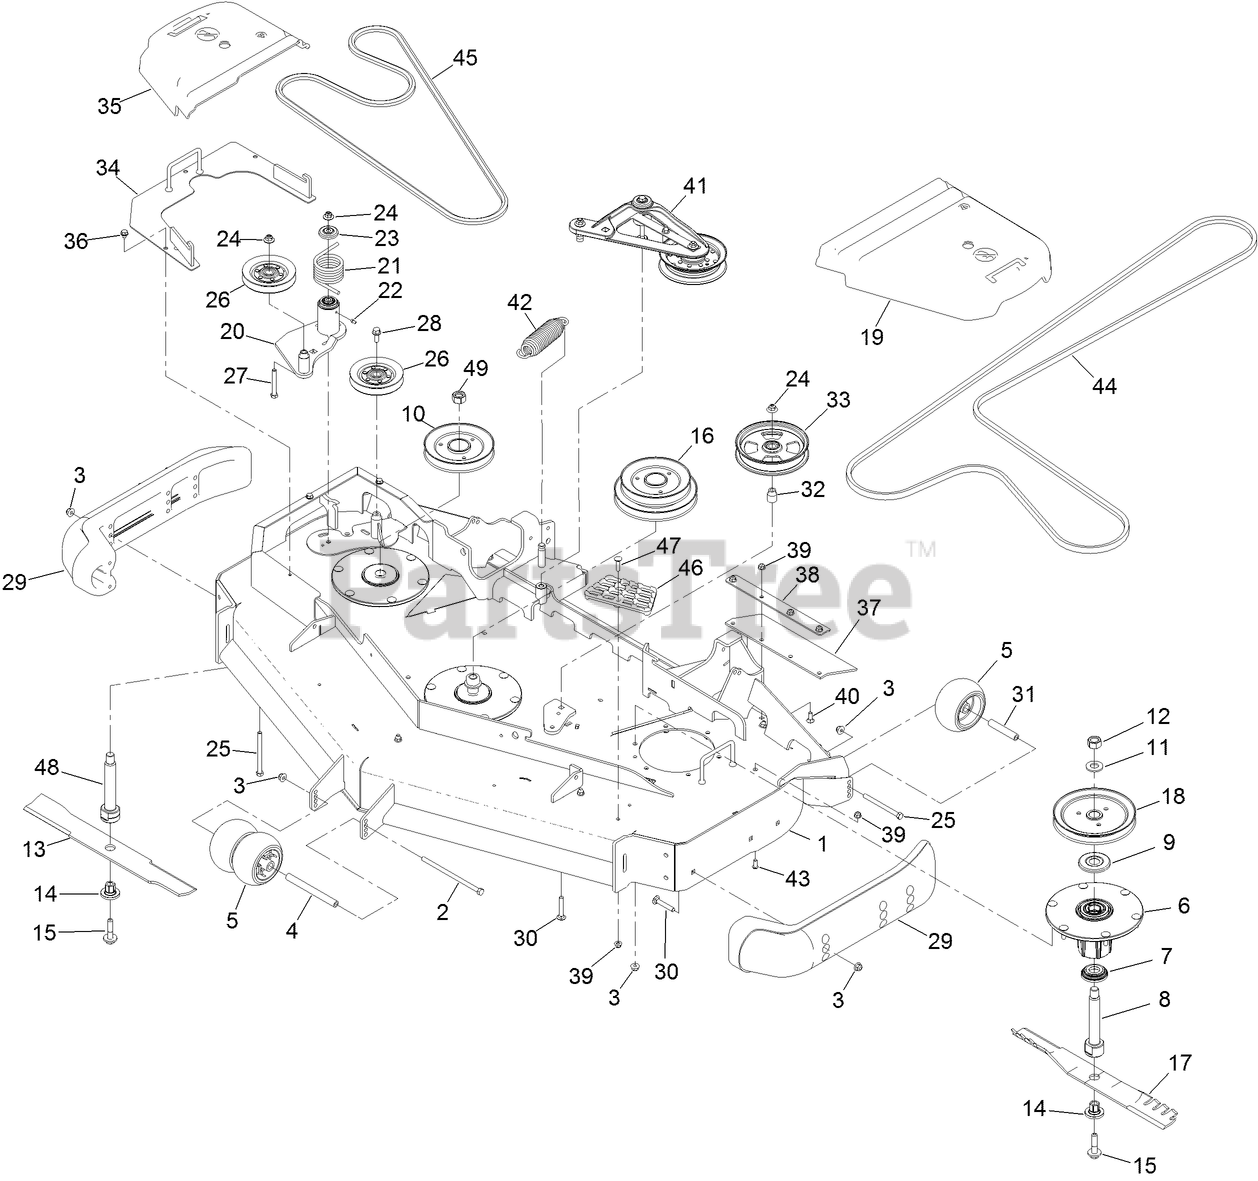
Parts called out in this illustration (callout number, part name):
1	DECK DECAL ASM
2	SCREW-HH
3	NUT-HF, NI
4	SPACER-WHEEL
5	ROLLER-SCALP, ANTI
6	SPINDLE ASM
7	GUARD-BOTTOM
8	SHAFT-SPINDLE
9	GUARD-BEARING, TOP
10	SHEAVE, DOUBLE BLADE DRIVE
11	WASHER
12	NUT-HEX
13	BLADE-20.50 CR LOW FLOW
14	BUSHING-HEX
15	SCREW-SEMS
16	SHEAVE, DOUBLE BLADE DRIVE
17	BLADE-20.50 ATOMIC
18	SHEAVE-DRIVE, BLADE
19	COVER-BELT, LH
20	IDLER ASM
21	SPRING-TORSION
22	FITTING-GREASE
23	GUARD-TOP
24	NUT-FLANGE, NI
25	SCREW-HH
26	SHEAVE
27	SCREW-HH
28	SCREW-HHF
29	SKID-BUMPER, DECK
30	SCREW-CARR
31	TUBE-SPANNER
32	BUSHING-IDLER
33	PULLEY-IDLER, FLAT
34	COVER-DRIVE REVERSE
35	COVER-BELT, RH
36	SCREW
37	GUARD-TIRE
38	SUPPORT-OUTER FLAP
39	NUT-HF, NI
40	SCREW-CARR
41	DECK IDLER ASM
42	SPRING-EXTENSION
43	SCREW-HSBH
46	STEP-DECK
47	SCREW-CARR
48	SHAFT-SPINDLE, INT. HEX LH THD
49	NUT-HEX,LH,LOCK
